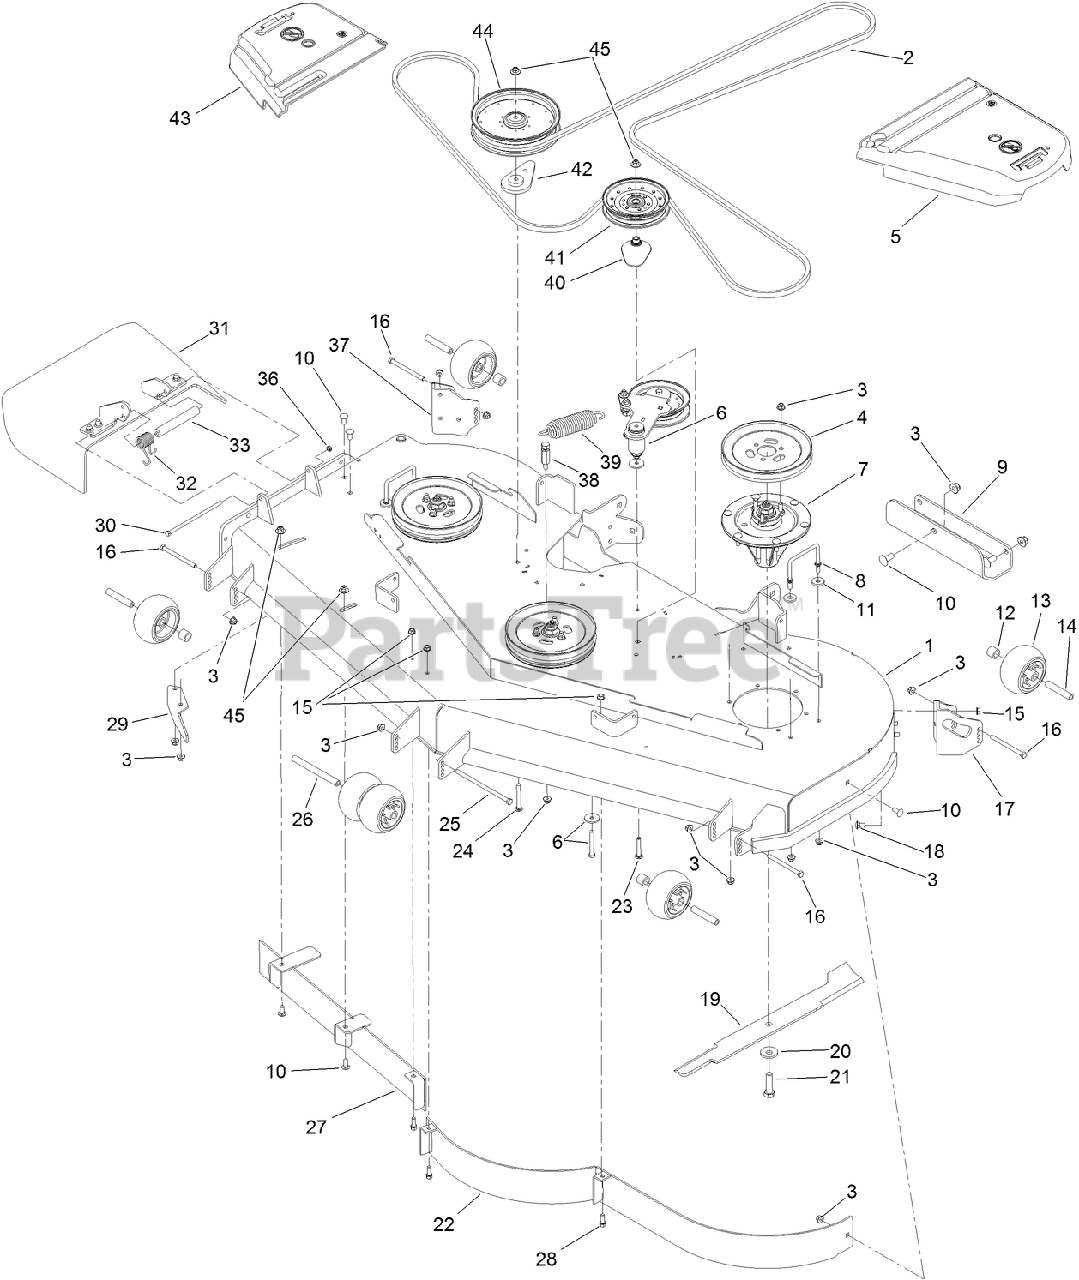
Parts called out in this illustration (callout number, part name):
1	DECK DECAL ASM
2	BELT-V
3	NUT-HF, NI
4	Pulley
5	COVER-BELT, LH
6	IDLER ARM ASM
7	SPINDLE ASM
8	WIREFORM-COVER
9	PLATE-SKID
10	SCREW-CARR
11	WASHER
12	TUBE-SPACER
13	ROLLER-SCALP, ANTI
14	TUBE-SPANNER
15	NUT-HHF, WHIZ
16	SCREW-HH
17	MOUNT-WHEEL, LH
18	SCREW-CARR
19	BLADE-HI FLOW, 24.5 INCH
20	Washer-Blade Bolt, Heavy
21	SCREW-BLADE
23	BOLT-CARR, SHORT NECK
24	SCREW-CARR
25	SCREW-HH
26	SPACER-WHEEL
28	SCREW-HWH
29	BAFFLE-DISCHARGE
30	SCREW-HH
31	RUBBER DEFLECTOR ASM
32	SPRING-TORSION
33	SPACER
36	NUT-LOCK, NI
37	MOUNT-WHEEL, RH
38	ANCHOR-SPRING, TALL
39	SPRING-EXTENSION
40	SPACER-PULLEY
41	PULLEY-IDLER, FLAT
42	SPACER-IDLER
43	COVER-BELT, RH
44	PULLEY-IDLER
45	NUT-FLANGE, NI
